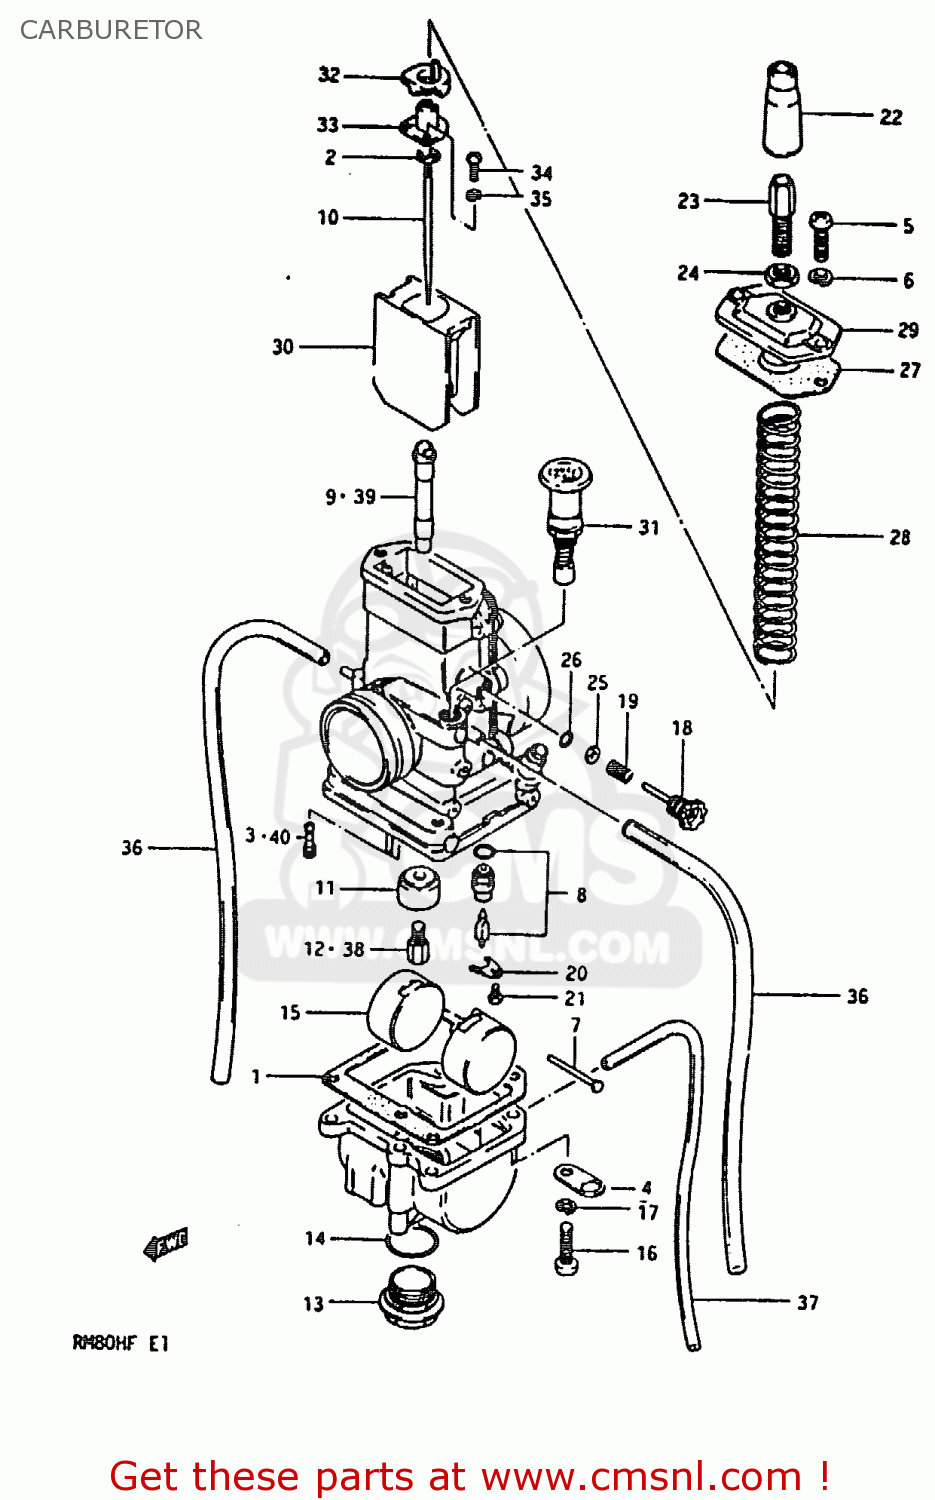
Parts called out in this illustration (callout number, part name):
1	GASKET,FLOAT CHAMBER (NAS)
2	CLIP
3	JET
4	PLATE,CARBURETOR
5	SCREW
6	LOCK WASHER
7	PIN,FLOAT
8	VALVE ASSY,NEEDLE
9	JET,NEEDLE
10	NEEDLE,JET(5DP39-4)
11	RING
12	JET,MAIN(170)
13	PLUG
14	O RING
15	FLOAT
16	SCREW
17	LOCK WASHER
18	ADJUSTER,THROTTLE STOP
19	SPRING
20	PLATE
21	SCREW
22	CAP,CABLE ADJUSTER
23	ADJUSTER,CABLE
24	NUT
25	WASHER
26	O RING
27	GASKET,CARBURETOR TOP (NAS)
28	SPRING
29	CAP,CARBURETOR TOP
30	VALVE,THROTTLE
31	VALVE ASSEMBLY,STARTER
32	RING
33	JOINT
34	SCREW
35	LOCK WASHER
36	HOSE
37	HOSE
38	JET
39	JET,NEEDLE
40	JET,PILOT(25)
